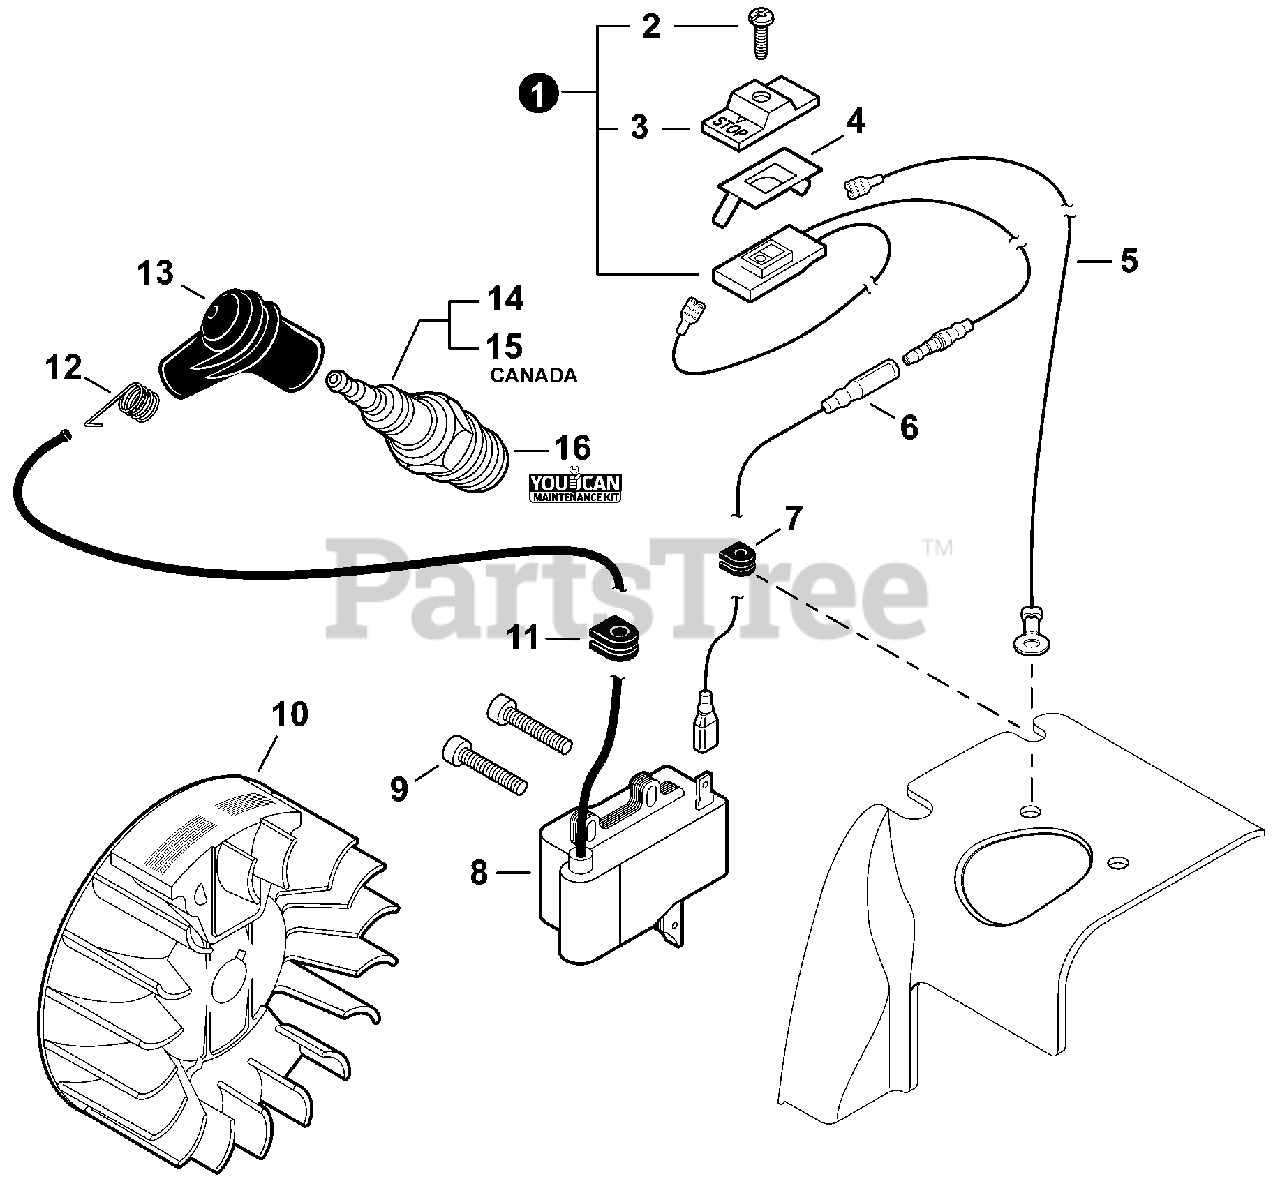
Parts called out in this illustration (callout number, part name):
1	SWITCH ASSY, ON-OFF
2	SCREW 3×10
3	KNOB, SWITCH
4	TERMINAL, LEAD
5	LEAD L= 210 MM
6	LEAD L= 85 MM
8	COIL, IGNITION
9	BOLT, TORX 4×20
10	FLYWHEEL
12	TERMINAL, SPARK PLUG
13	CAP, SPARK PLUG
14	SPARK PLUG - BPM8Y
15	SPARK PLUG - BPMR8Y
16	TUNE-UP KIT - YOUCANT
